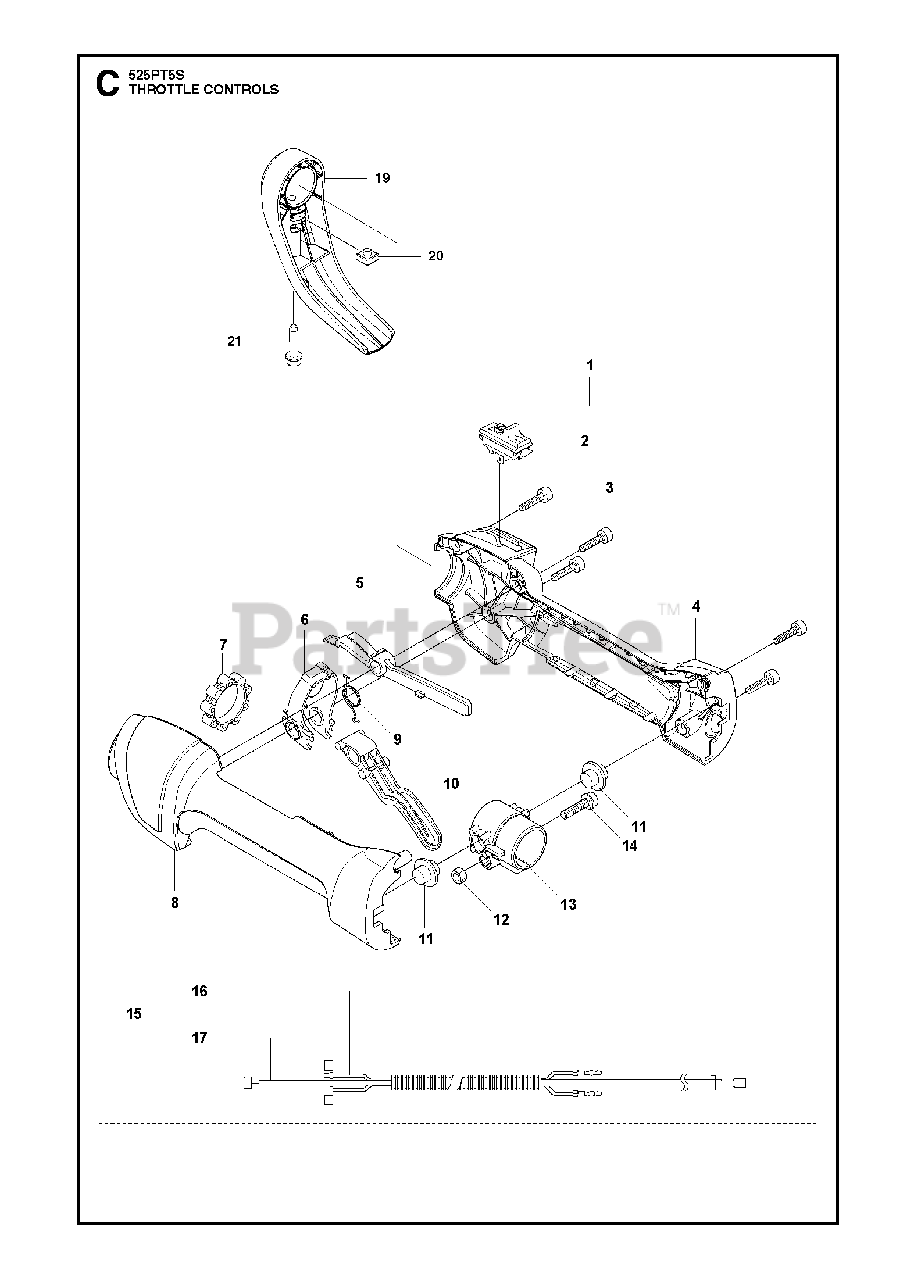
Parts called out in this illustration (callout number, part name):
1	THROTTLE CONTROL
1	THROTTLE CONTROL ASSY
2	STOP BUTTON
3	SCREW
4	HANDLE
5	THROTTLE LOCK
6	LEVER
7	VIBRATION DAMPER
8	HANDLE
9	RETURN SPRING
10	THROTTLE TRIGGER
11	VIBRATION ABSORBER
12	NUT
13	HOLDER
14	BOLT TORX
15	WIRING ASSY
16	SHORT CIRCUIT CABLE
17	THROTTLE CABLE
19	TRIGGER
20	SQUARE NUT M5
21	SCREW IHSCFM M5223 10.9 ZN/FE
